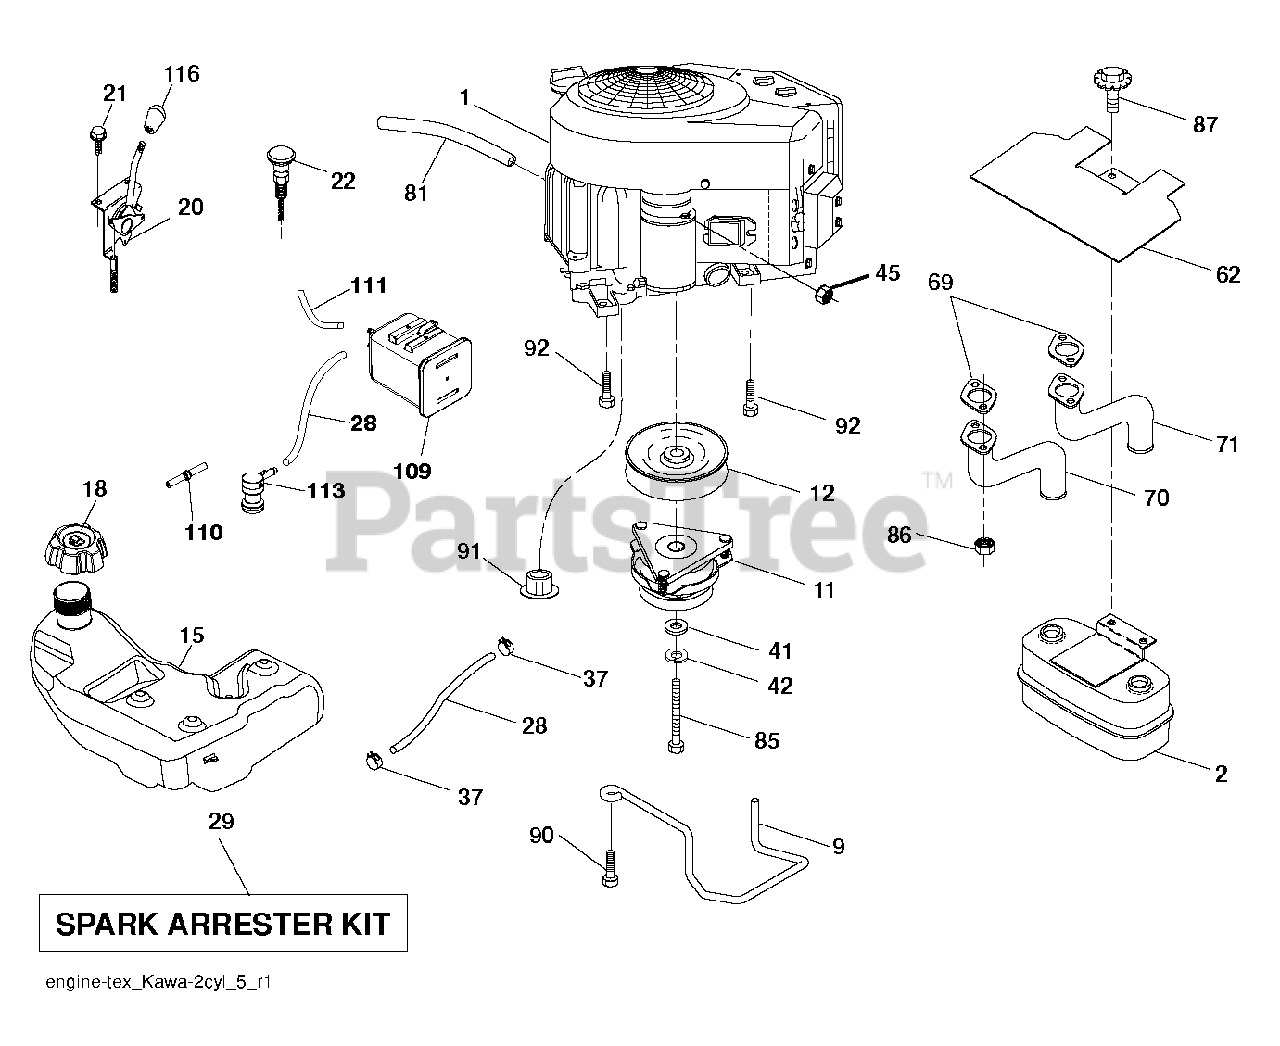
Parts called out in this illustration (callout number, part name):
2	MUFFLER.ASM.TWN.EXTNDED.DFLCTR
9	KEEPER.BELT.ENGINE.4.2
11	CLUTCH.ELECTRIC.LT.48"*
12	PULLEY.ENGINE.TUFFTORQ
15	TANK.ASM.FUEL.3GA.CARB
18	CAP.ASM.FL.RITCH.3"E10.SYM.498
20	CONTROL.THROTTLE.PRO.
21	SCREW.#10 X 0.750.BOS
22	CONTROL, CHOKE
28	LINE.FUEL.64"REAR.EMIS
29	KIT.SPARK ARRESTOR 794945 B&S
37	HOSE CLAMP
42	LOCKWASHER
45	NUT
62	SHIELD.HEAT.MUFFLER
70	TUBE.EXHAUST.LH.FR961/FR730
71	TUBE.EXHAUST.RH.FR961/FR730
81	TUBE, DRAIN OIL ASM.
85	BOLT HEX 7/16-20X4-1/4"
86	NUT.HEX.FLANGE.TOPLOCK
87	Bolt, 5/16-18 X 1-3/4
90	SCREW 3/8-16X1
91	BUSHING.1.375OD
92	SCREW 3/8-16X1
109	CANNISTER, CARBON
110	VALVE.ASM.ANTI-SLOSH
111	RP PURGE LINE
113	VALVE.SLANT.CARTRDG.90 DEG.TEX
116	KNOB - SHIFT
